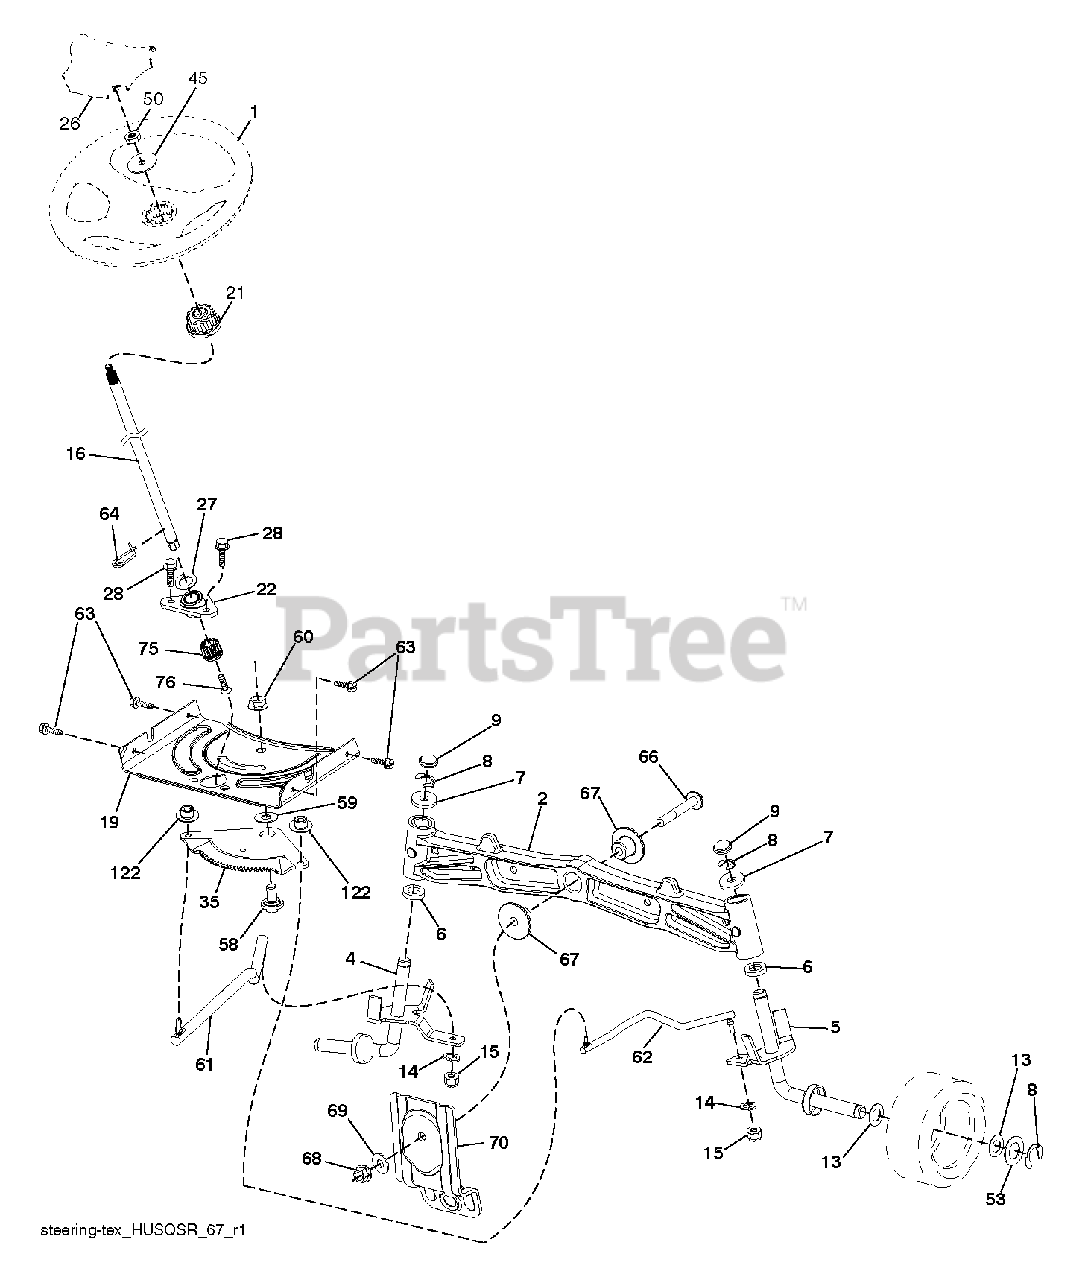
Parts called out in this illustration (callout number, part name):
1	WHEEL.STEER.HUSQ.SR.498.OVMLD
2	AXLE.CAST.IRON
4	SPINDLE.WELDED.LH.15"TEX
5	SPINDLE.WELDED.RH.15"T
6	THRUST WASHER
9	CAP.SPINDLE.BLACK
14	WASHER, LOCK 3/8
15	NUT CROWNLOCK 3/8-24
16	SHAFT.STEER.2HIGH.SPLND.PLATED
19	PLATE.STEER.DDL.NLT/NG
21	ADAPTER.WHEEL.STEER.SPLND.ALUM
22	BEARING.SHAFT.STEER.LOWER.625
26	INSERT.CAP.WHL.STRG.HUSQ.PREM
28	SCREW, 3/8-16X3/4
35	GEAR.SECTOR.PLATE.DDL.
45	WASHER.3/8ID.2-3/8OD.12GA.PLTD
50	NUT LOCK FLG 3/8-16 UNC
53	WASHER.HARDENED
58	BOLT.SHOULDER.SECTOR.P
59	WASHER.THURST.SECTOR.S
60	NUT FLANGE LOCK 5/8-11
61	LINK.ASM.DRAG.ADJUST.LH.RAW
62	LINK.ASM.DRAG.ADJUST.RH.RAW
63	SCREW
64	RETAINER.CLIP.SPRING.S
66	BOLT HEX FGHD 7/16-14 X 3 SERR
67	BUSHING.PM.FRONT AXLE
68	NUT.LOCK.FLANGE.7/16
69	WASHER.1.5X.505X.118
70	BRACKET.FRT.DECK.SUSP.RR.MT431
75	PINION.ZINC PLATED
76	SCREW HEAD SOCKET LRVB
122	CAP.GEAR.SECTOR.TEX
